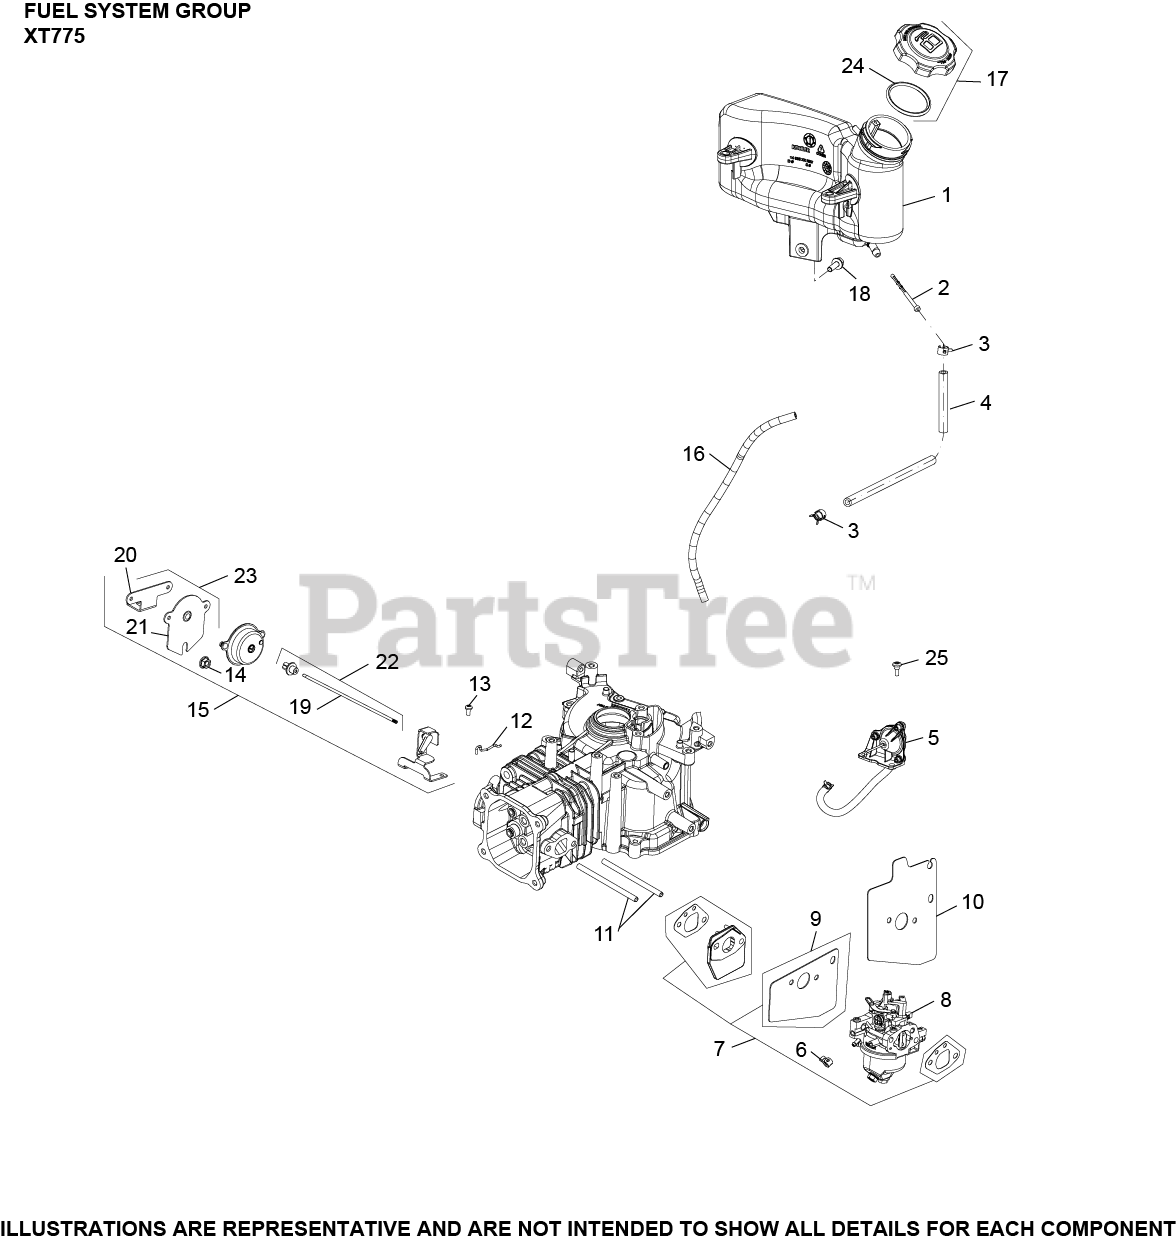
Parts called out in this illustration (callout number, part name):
1	TANK, FUEL 1.4L FOR EUROPE ONLY
2	FILTER, FUEL IN-NIPPLE
3	CLAMP, HOSE
4	HOSE, FUEL LOW-PERMEATION
5	DIAPHRAGM, ASSEMBLY
6	CLAMP, HOSE
7	KIT, SPACER
8	KIT, CARBURETOR 13MM AUTO CHOKE
9	KIT, CARBURETOR HEAT SHIELD GASKET
11	STUD,M6X1.0X100.2MM
12	LINKAGE AUTO CHOKE
13	SCREW, M4 THREAD FORMING
14	NUT, HEX FLANGE (M6)
15	ARM ASSEMBLY, AUTO CHOKE
16	HOSE, EVAPORATIVE
17	CAP ASSEMBLY, FUEL
18	SCREW, THREAD FORMING USE 25 086 472-S
19	SHAFT, AUTO CHOKE - DISCONTINUED
20	BRACKET, AUTO CHOKE MUFFLER-DISC.
21	BRACKET, HOUSING AUTO CHOKE-DISC.
22	SHAFT SUB ASSEMBLY - DISCONTINUED
23	BRACKET, HOUSING AUTO CHOKE-DISC.
24	SEAL, FUEL CAP
25	SCREW, SHOULDER
